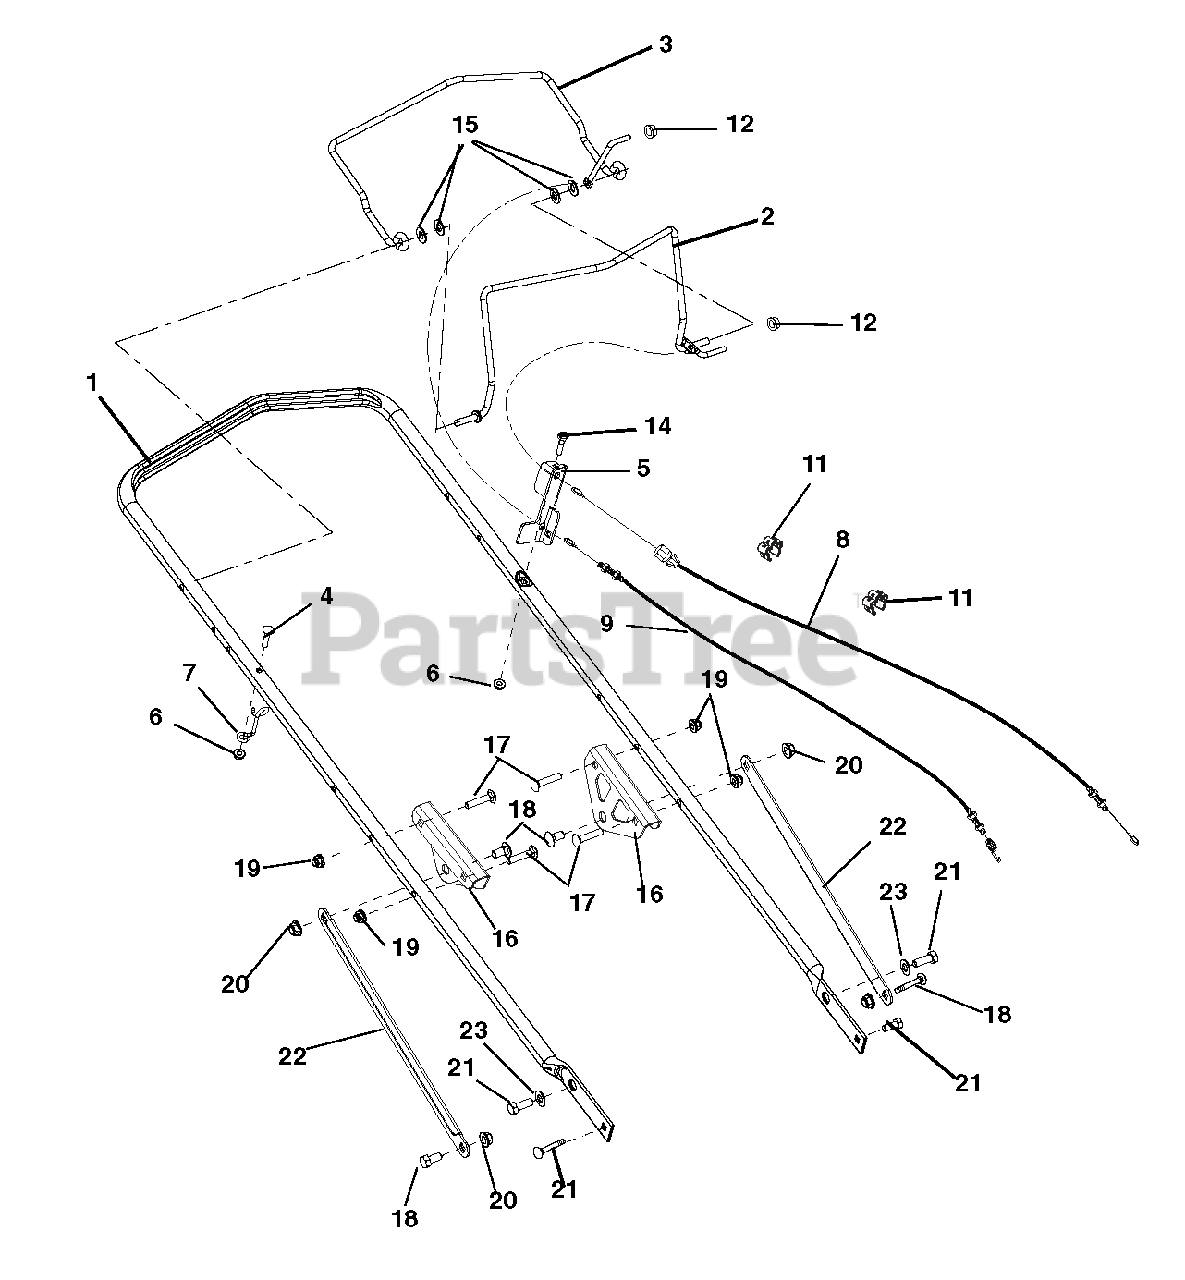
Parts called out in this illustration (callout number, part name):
1	HANDLEBAR, XD21 - 2010
2	WLDMT, OPC BAIL - COMM 21
3	WLDMT, TRACTION BAIL - COMM 21
4	BLT-RDHDXLSQNK.25-20X1.25 G5ZC
5	ANCHOR, CABLE
6	@NUT-LK-TOP-FLG .25-20 YWZC
7	GUIDE - PULLCORD
8	CABLE, ENGINE - ADJUSTABLE
9	CABLE, COMMERCIAL 21 TRACTION
10	@BLT-HEX .31-18X.75 GR5 YWZC
11	CONDUIT CLIP
12	PUSH NUT, .25
13	PLATE,HINGE
14	@BLT-HEX .25-20X1.25 GR5 YWZC
15	@WSHR-FL-STL.344X.688X.065YWZC
16	BRKT, HANDLEBAR REINFORCEMENT
17	@BLT-RDHDSQNK .31-18X1.50 G5YZ
18	@BLT-RDHDSQNK .38-16X.75 G5YZ
19	@NUT-LK-NYL-FLG .31-18 YWZC
20	@NUT-LK-NYL-FLG .38-16 YWZC
21	@BLT-HEX .38-16X.75 GR5 YWZC
22	STRAP,HANDLEBAR
23	@WSHR-FL-STL.406X.812X.065 YWZ
